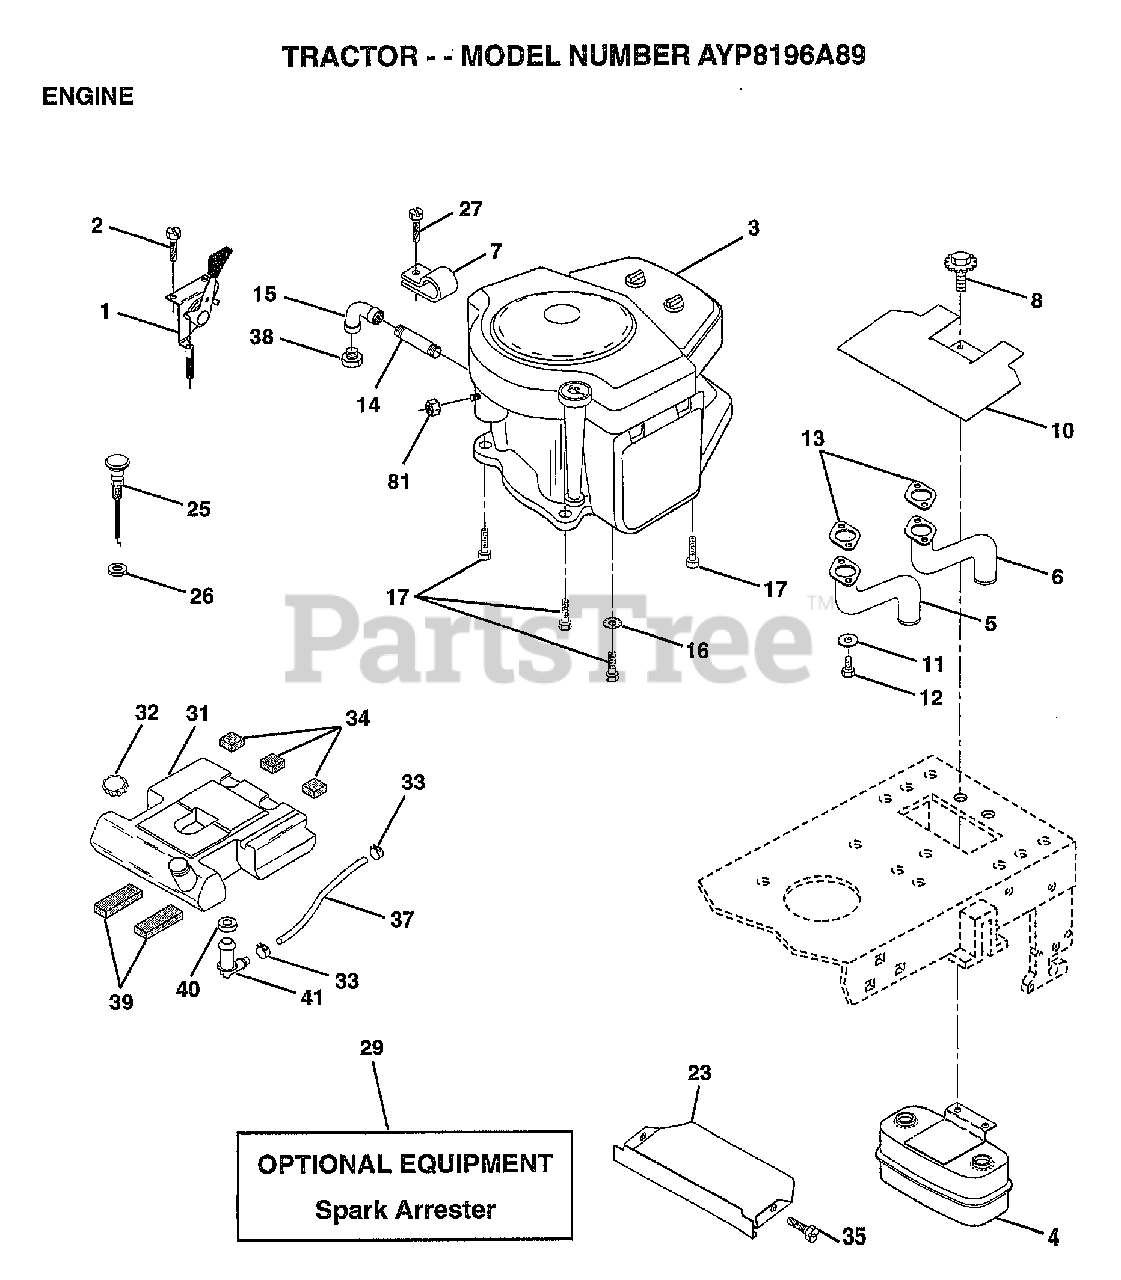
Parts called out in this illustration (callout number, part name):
1	CONTROL THRT 35.5
2	SCREW LT
4	MUFFLER.TW.LOTONE
5	EXHAUST.B&S.18.RH
6	EXHAUST.B&S.18.LH
7	CLAMP.TUBE.DBL.EN
8	BOLT.5/16-18.UNC
10	SHIELD.HEAT.
11	LOCKWASHER
13	GASKET MUFFLER
14	PIPE NIPPLE LT
15	ELBOW
16	LOCKWASHER
17	SCREW LT
23	SHIELD.BRN/DBR.GD
25	CONTROL.CHOKE.37
26	"NUT,KEPS 3/8-24IM"
27	"SCREW-TT,10-32 FL"
31	TANK FUEL REAR
32	CAP ASM FUEL
33	HOSE CLAMP
34	PAD-SPACER LT
35	SCREW
37	FUEL LINE T
39	PAD IDLER TI
40	BUSHING OUTLET T
41	STEM.TANK.FUEL
81	NUT
